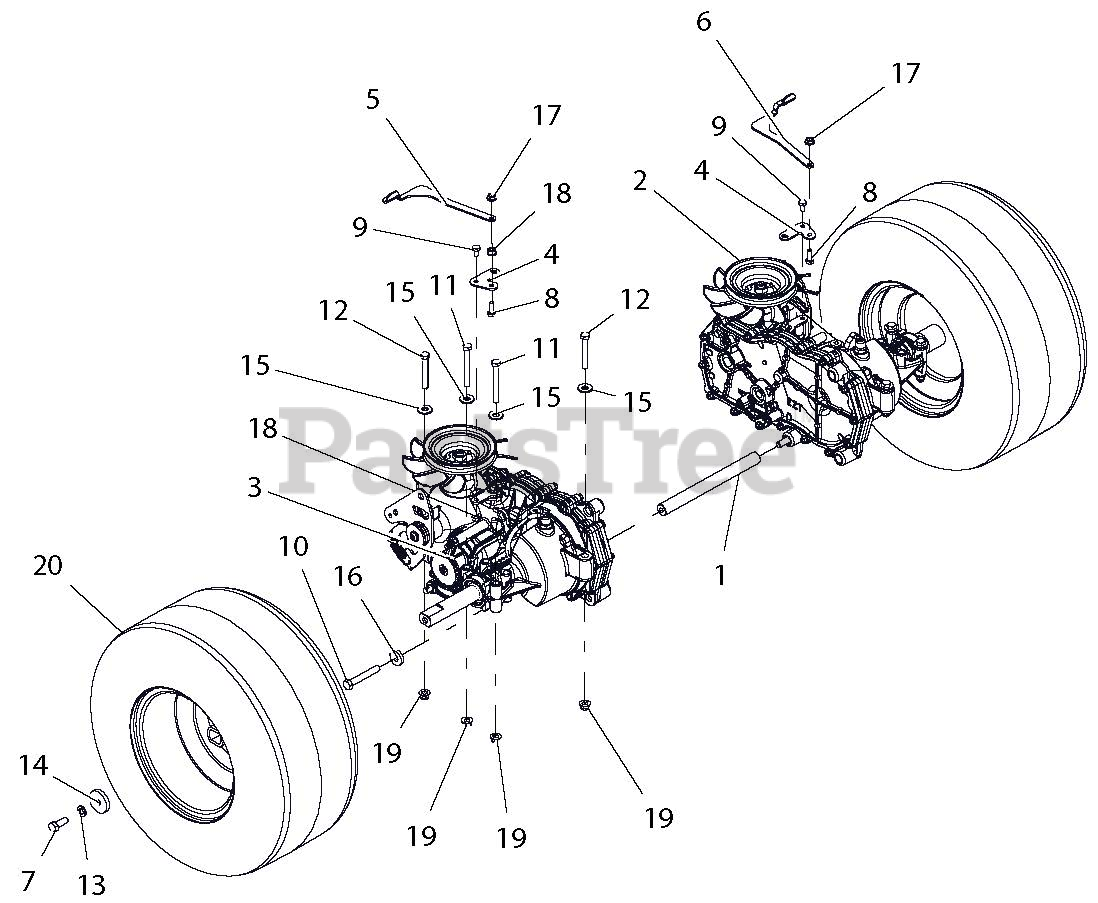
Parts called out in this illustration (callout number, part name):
1	ROD, TRANSAXLE BRACE
2	TRANSAXLE,LH EZT D-SHFT SHORT
3	TRANSAXLE,RH EZT D-SHFT SHORT
4	BRKT, DUMP VALVE EXTENSION
5	BRKT, DUMP VALVE RH
6	BRKT, DUMP VALVE LH
7	BLT-HEX .38-16X1.0 GR8 YZ EP30
8	@BLT-HEX .25-20X.75 GR5 YWZC
9	@BLT-HEX .25-20X.50 GR5 YWZC
10	@BLT-HEX .38-16X2.50 GR5 YWZC
11	@BLT-HEX .31-18X2.75 GR5 YWZC
12	@BLT-HEX .31-18X2.25 GR5 YWZC
13	@WSHR-LK .38X.094 REG YWZC
14	WSHR,FLT STL.406X1.50X.245YWZC
15	@WSHR-FL-STL.38X.875X.083 YWZC
16	WSHR-FL-STL .406X1.00X.188 YWZ
17	@NUT-SPNLK-FLG .25-20 YWZC
18	@NUT-LK-TOP-FLG .25-20 YWZC
19	@NUT-LK-NYL-FLG .31-18 YWZC
20	TIRE/WHEEL ASSY,18X8.50-8 DHUB
